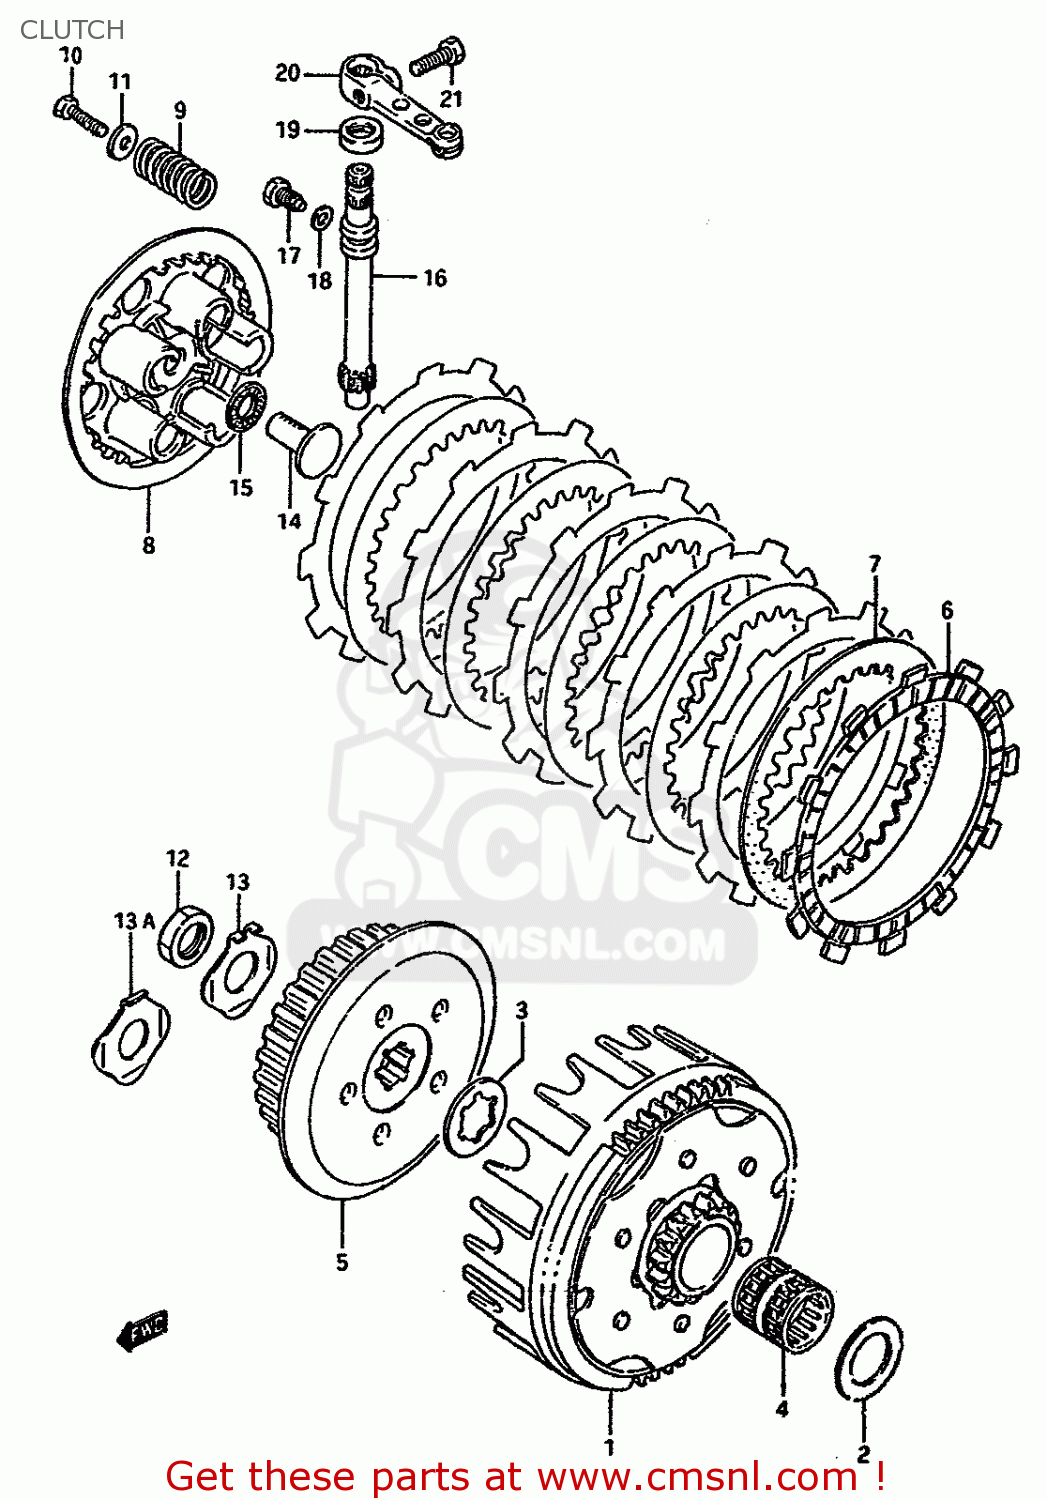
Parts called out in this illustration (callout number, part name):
1	GEAR ASSEMBLY,PRIMARY DRIVE
2	WASHER,THRUST
3	WASHER,LOCK
4	BEARING(20X25X26)
5	HUB,CLUTCH SLEEVE
6	PLATE,CLUTCH DRIVE (NAS)
7	PLATE,DRIVEN(T:1.4)
8	DISC,CLUTCH PRESSURE
9	SPRING
10	BOLT(5X16)
11	WASHER (5.5X16X1.2)
12	NUT
13	WASHER
13A	WASHER
14	RACK,CLUTCH RELEASE
15	BEARING(10X22X2.8)
16	PINION,CLUTCH RELEASE
17	BOLT
18	GASKET(6.2X11X1).2 (NAS)
19	SEAL,OIL(10X17X5)
20	ARM,CLUTCH RELEASE
21	BOLT
